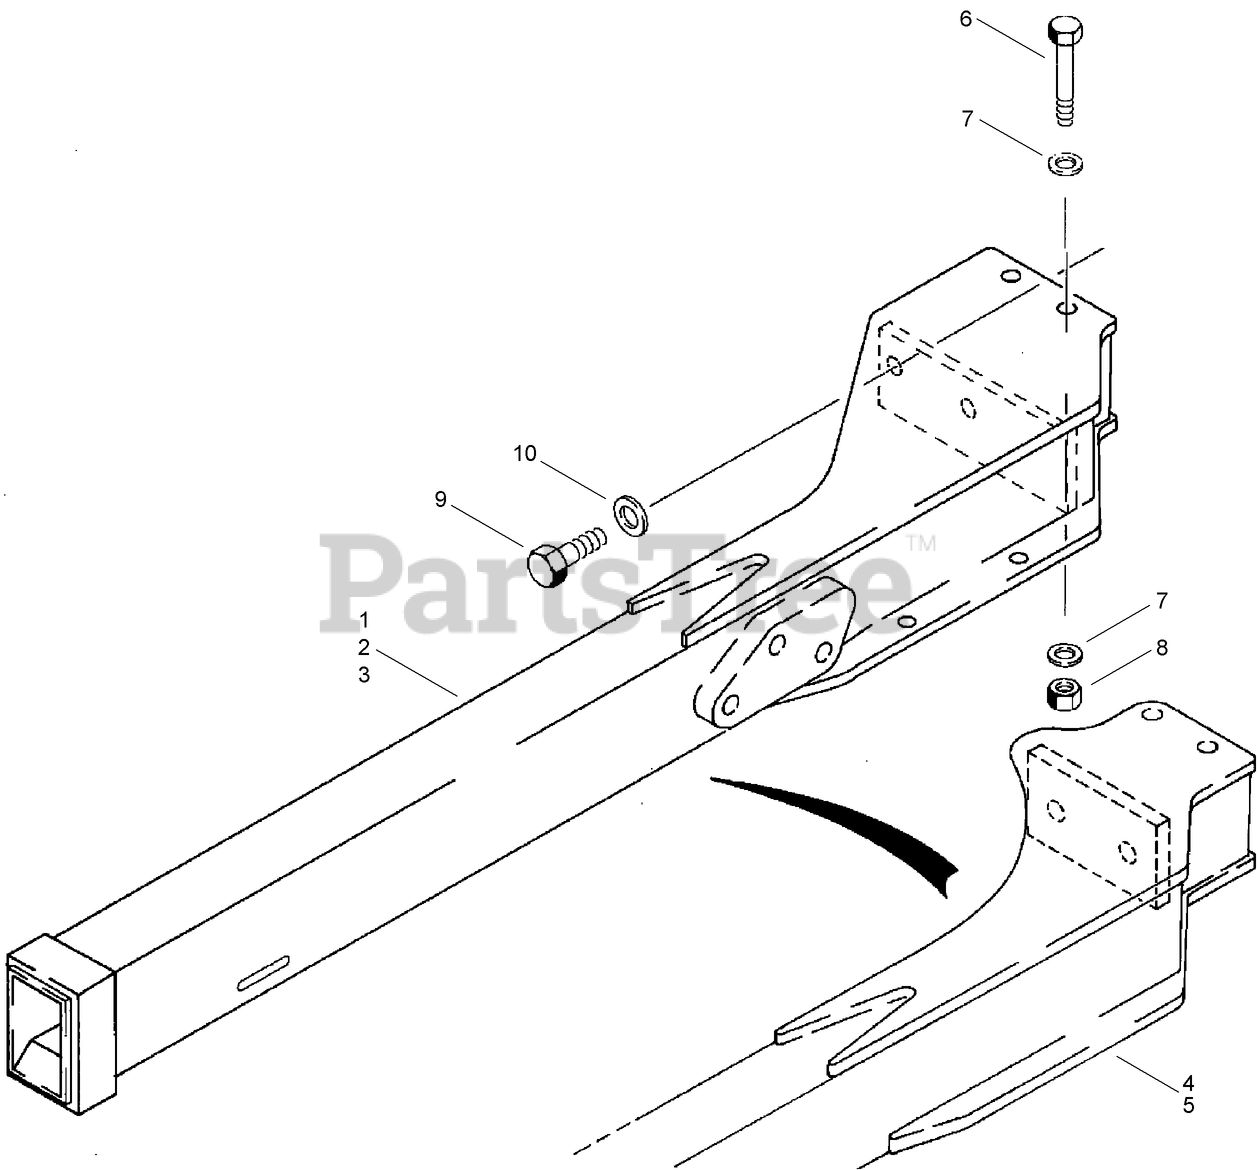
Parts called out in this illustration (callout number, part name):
1	BOOM-trencher, 4 foot, heavy duty planetary drive trencher
2	BOOM-trencher, 5 foot, heavy duty planetary drive trencher
3	BOOM-trencher, 6 foot, heavy duty planetary drive trencher
4	BOOM-trencher, 4 foot, direct drive trencher
5	BOOM-trencher, 5 foot, direct drive trencher
6	SCREW-HH
7	WASHER-flat, special, 3/4 inch
8	NUT-Prev Trq 3/4 GRC CAD Direct
10	WASHER-flat, special, 1-1/16 x 1-7/8 x 9/64 inch
